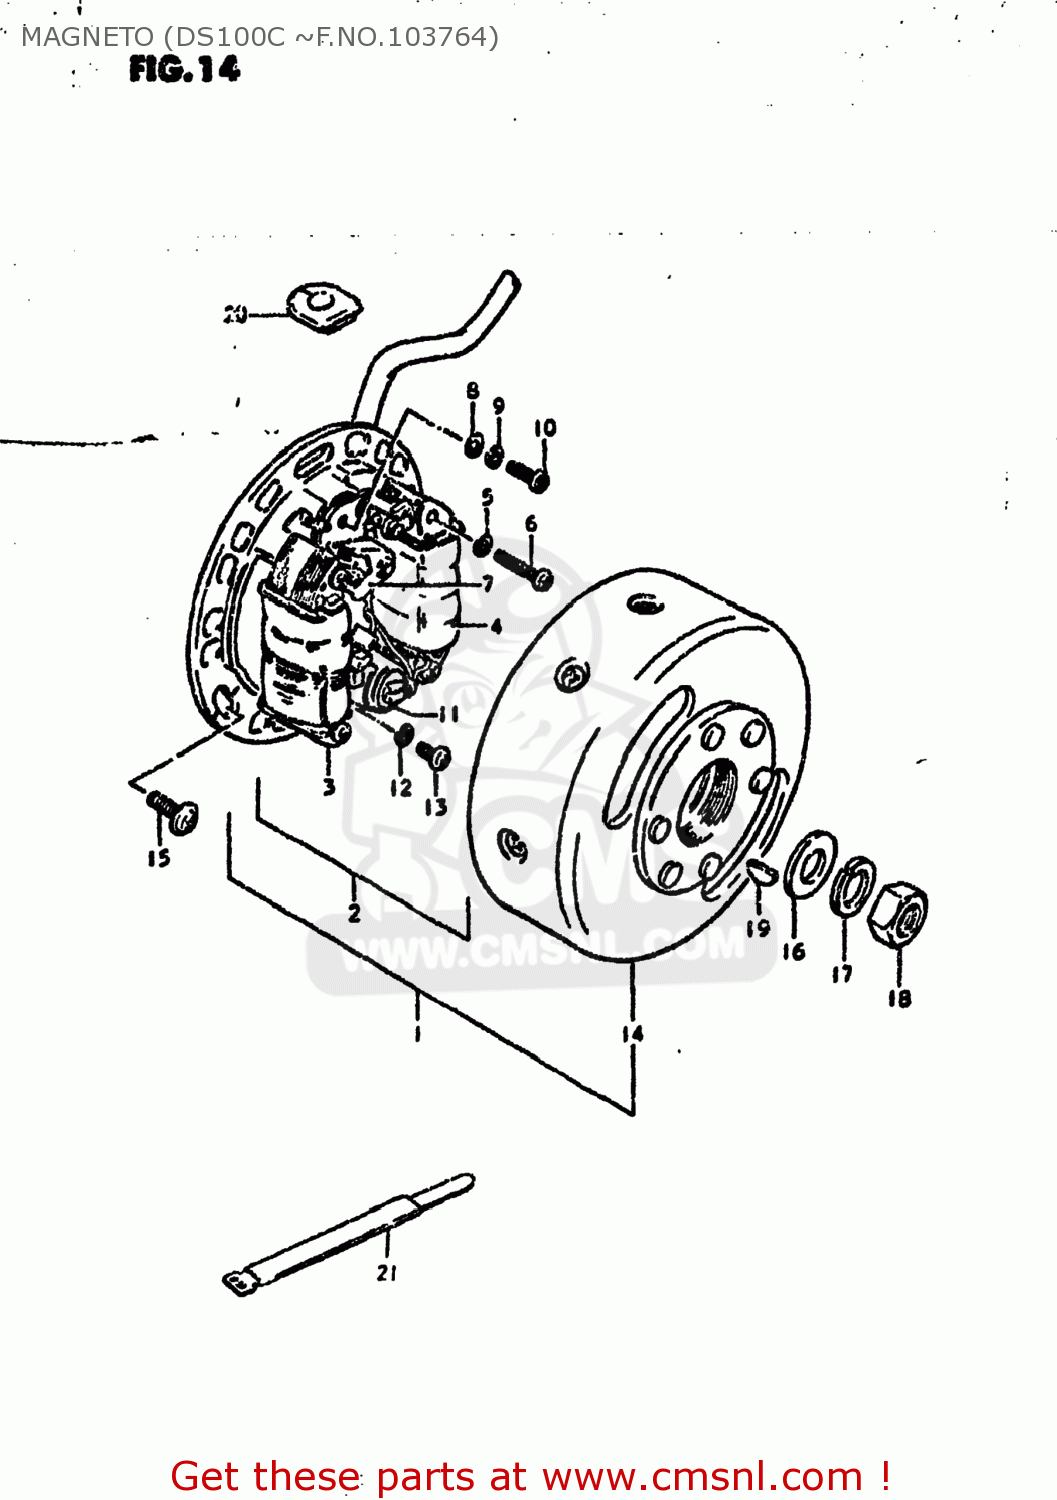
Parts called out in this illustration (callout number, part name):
1	MAGNETO ASSEMBLY
2	STATOR ASSEMBLY
3	COIL,LIGHTING
4	COIL,PRIMARY
5	LOCK WASHER
6	SCREW 4X25
7	POINT ASSY,CONTACT
8	WASHER
9	LOCK WASHER
10	SCREW(4X10)
11	CONDENSER
12	LOCK WASHER
13	SCREW 4X10
14	ROTOR ASSEMBLY
15	SCREW(5X14)
16	WASHER
17	LOCK WASHER
18	NUT (10MM)
19	KEY
20	GROMMET
21	CLAMP
